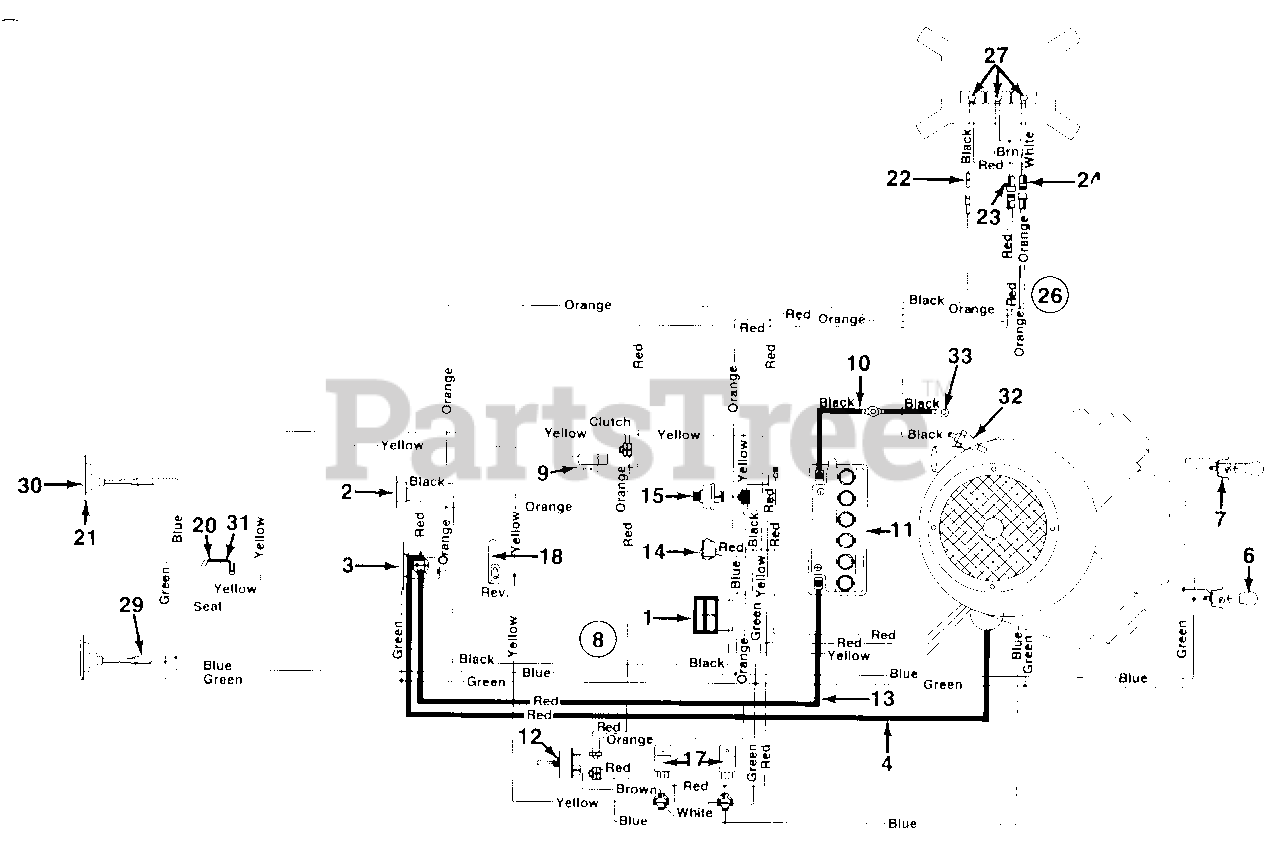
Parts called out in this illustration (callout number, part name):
1	Ammeter
2	Circuit Breaker
3	Solenoid
4	Wire 30" Lg.
6	Bulb
7	Socket
8	Wire Harness
9	Safety Switch (Clutch)
10	6 Ga. Black Wire
11	Battery 12V (275 Cold Crank Amps)
12	Switch (PTO)
13	Wire 27" Lg.
14	Light Switch
15	Ignition Switch
17	Relay
18	Spring Lever
20	Safety Switch (Seat)
21	Taillight
22	Connector
23	Connector
24	Connector
26	Wire Harness
27	Bulb
29	Taillight Harness
31	Safety Switch (Seat)
32	Oil Pressure Switch
33	Wire 7.5" Lg.
